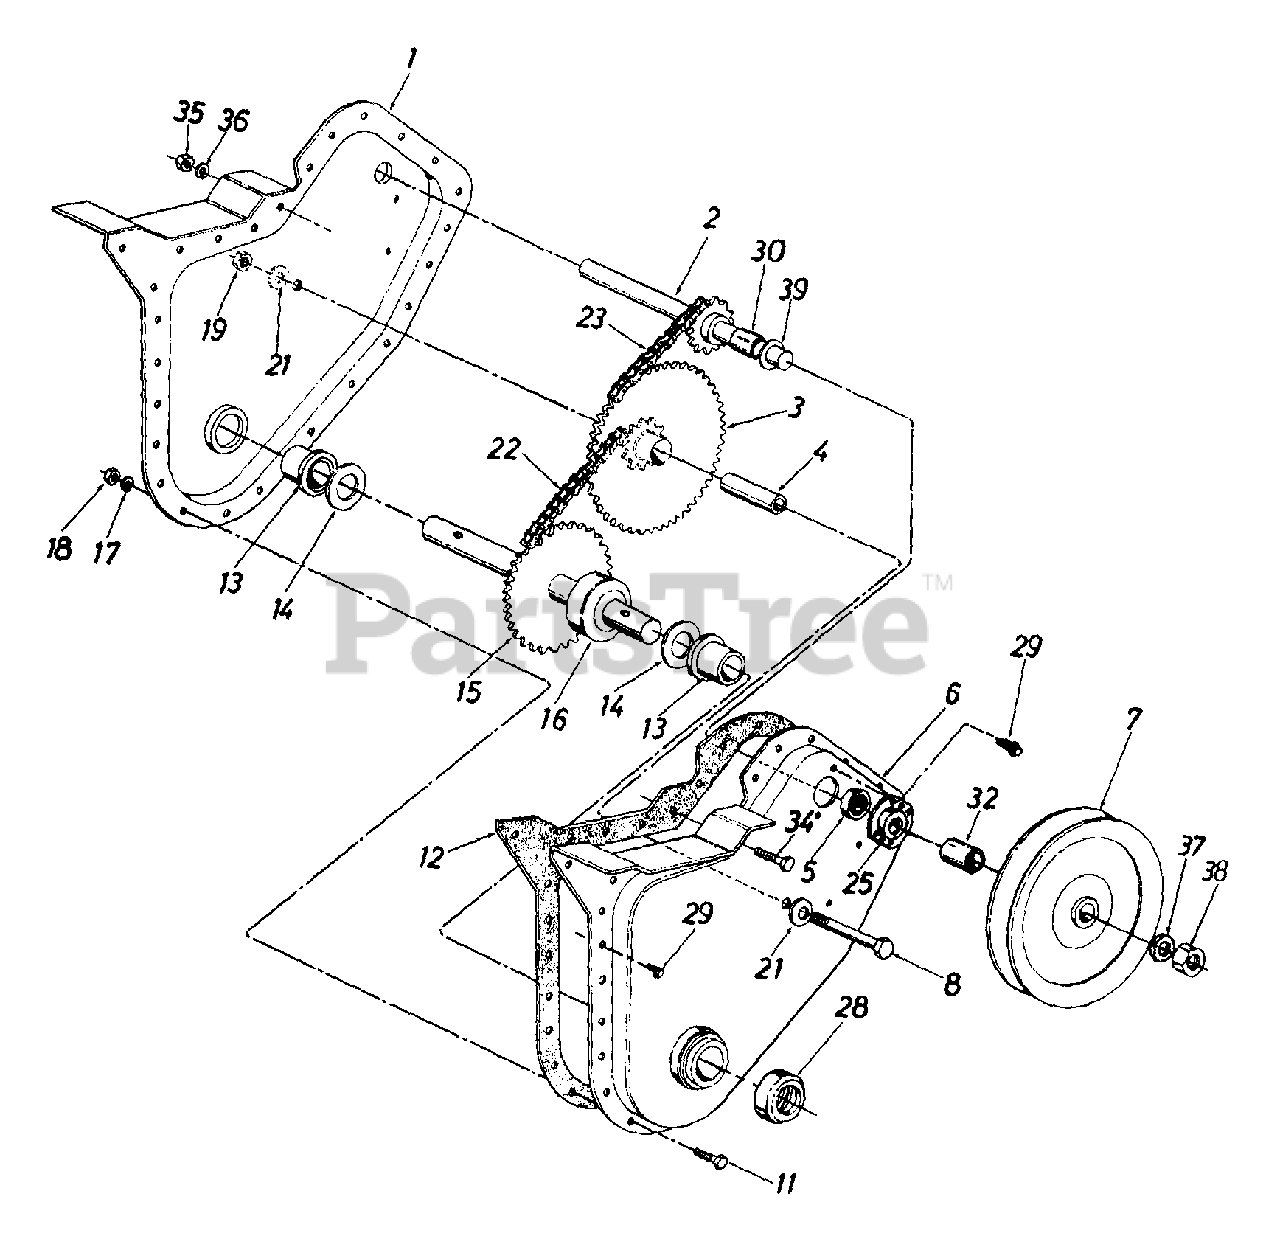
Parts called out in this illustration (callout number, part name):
1	Chain Case Ass'y. - R.H.
2	Input Shaft Ass'y.
3	Hub and Sprocket Ass'y.
4	Bearing Inner Race
5	Ball Bearing
6	Chain Case Ass'y. - L.H.
7	Pulley - Chain Case
8	Hex Bolt 3/8-24 x 2.5"
11	Hex Bolt 1/4-28 x .625"
12	Gasket
13	Flange Brg. .879" I.D.
14	Fl-Wash. .88" I.D. x 1.5"
15	Tine Shaft Ass'y.
16	Spacer 7/8" I.D.
17	L-Wash. 1/4" I.D.
18	Hex Nut 1/4-28 Thd.
19	Hex Ins. L-Nut 3/8-24 Thd.
21	Bell-Wash. .406" I.D.
22	Chain #420 1/2" Pitch 38 Links
22	#420 Master Link
23	Chain #35 .375" Pitch 50 Links
23	#35 Master Link
25	Bearing Housing
28	Shaft Seal
29	Hex Wash. Hd. Self-Tap Scr. 1/4-20
30	Spacer .63" I.D. x .77" O.D. x .38" L
32	Spacer .647 x .77"
34	Hex Bolt 5/16-18 x .75" Lg.
35	Hex Nut 5/16-18 Thd.
36	L-Wash. 5/16" I.D.
37	Bell-Wash. .38" I.D. x .88" O.D.
38	Hex Flange L-Nut 3/8-24 Thd.
39	Washer .652 I.D.
